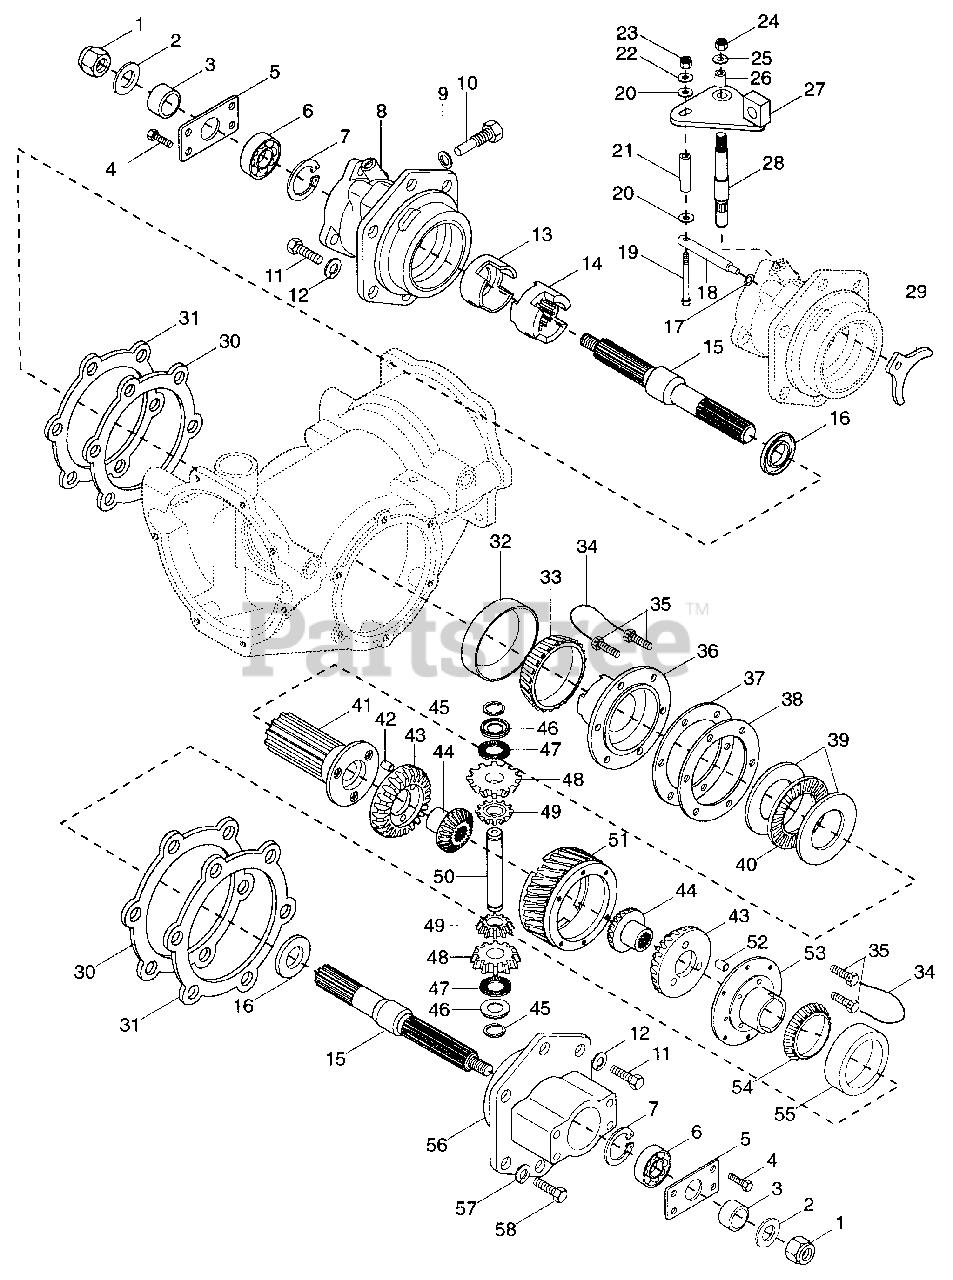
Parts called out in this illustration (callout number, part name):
1	Nut-Locking-Jam-Nylon .75-10
2	Washer-Flat .812 x 1.469 x .134
3	Bushing, Sleeve 1.02 x 1.37 x .509
4	Bolt-Hex .38-16 x .75 Grade 5
5	Plate, End
6	Bearing-Ball 1.0 x 2.0 x .56
7	Ring-Retaining-lnternal 2.210 x .062
8	Housing, Axle, 2 Speed
9	Washer-Nut .63 x .875 x .062
10	Bolt-Hex .62-18 x .493 x 1.25
11	Bolt-Hex .50-13 x 1 Grade 5
12	Washer-Lock .50
13	Clutch, Stationary
14	Clutch, Shifting
15	Axle, Straight
16	Seal 1.188 x 2.000 x .250
17	O-Ring .437 x .625 x .093
18	Pin, Clutch Sliding
19	Bolt-Round Head Square Neck .25-20 x 2.25
20	Washer-Flat-Steel .406 x .812 x .065
21	Bushing, Sleeve .277 x .375 x 1.37
22	Washer-Flat-Steel .281 x .625 x .065
23	Nut-Locking-Nylon .250-20
24	Nut-Locking-Nylon .312-18
25	Washer-Flat-Steel .344 x .688 x .065
26	Bushing-Sleeve .377 x .503 x .88
27	Weldment, Arm Shifter
28	Pivot, Stationary
29	Yoke, Shifting
30	Gasket, Axle Housing
31	Shim, Axle Housing .005
32	Bearing-Race 4.34 x .741
33	Bearing-Cone 2.69 x .87
34	Wire, Bolt
35	Bolt-Special .31-18 x .75
36	Housing, Clutch
37	Shim, .020 Clutch Worm Gear
38	Shim, .005 Clutch Worm Gear
39	Washer-Thrust 2.002 x 2.740 x .031
40	Bearing-Needle-Thrust 2.0 x 2.74 x .010
41	Shifter, Splined Pinned
42	Pin-Dowel .375 x .375
43	Gear, Pinned Bevel
44	Gear, Differential Bevel
45	Ring-Retaining .697 x .93
46	Bushing-Flange .761 x 1.24 x 1.24
47	Bearing-Neede-Thrust .754 x 1.24 x .078
48	Gear, Differential Shifting Bevel
49	Gear, Spider Bevel
50	Pin, Spider
51	Gear, Worm 8 Start
52	Pin-Dowel .38 x .500
53	Housing, Pinned
54	Cone, Roller Bearing; 50 MM x 21.5 MM
55	Cup, Roller Bearing; 82 MM x 17 MM
56	Housing, Axle
57	Seal-Oil Drain .563 x 1.250 x .091
58	Bolt-Hex .50-13 x 1.312 Grade 5
